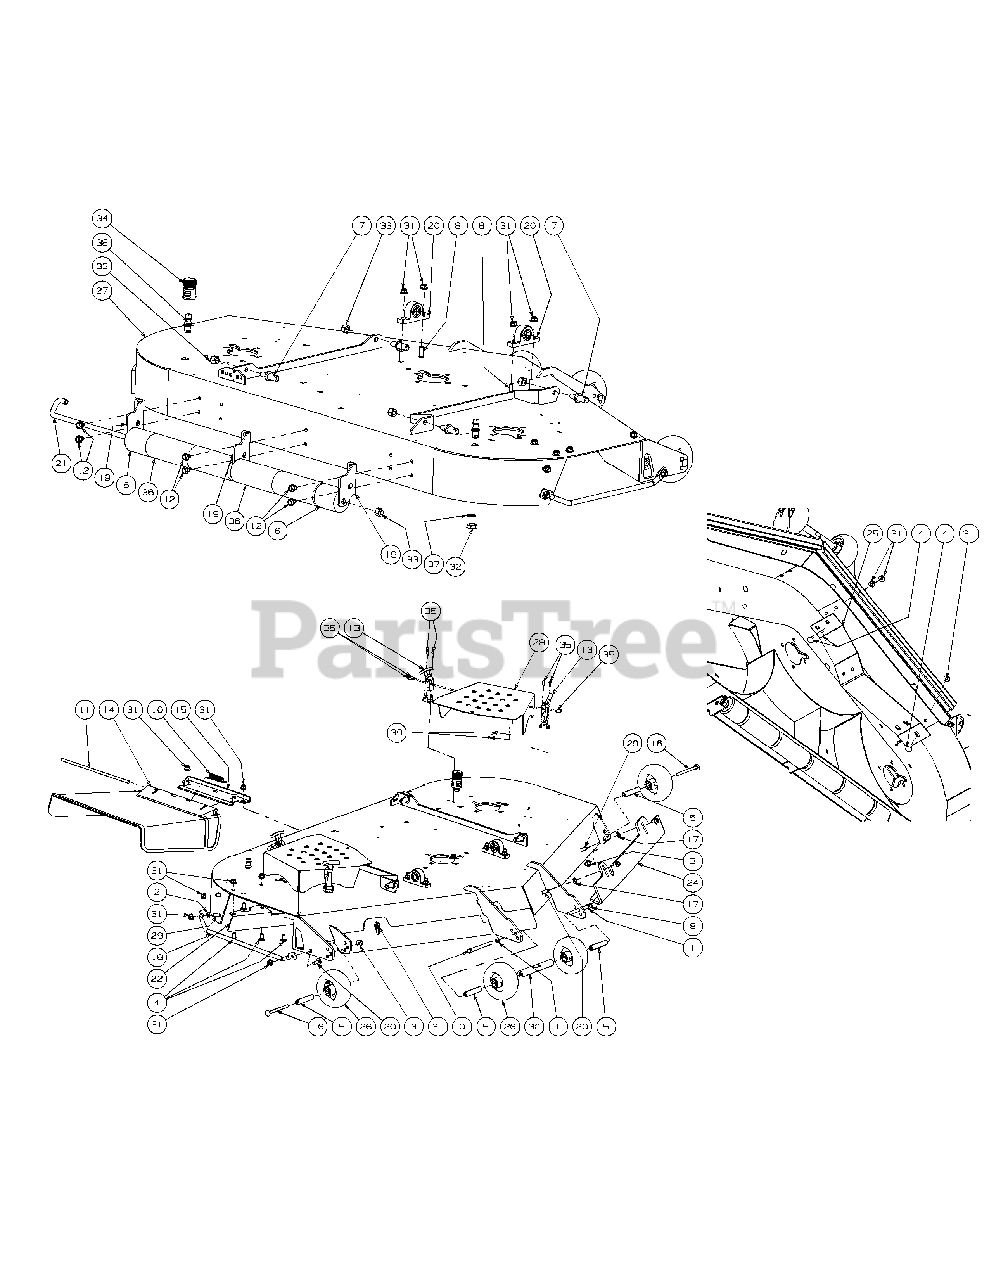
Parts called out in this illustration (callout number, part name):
1	Lock Washer, 3/8
2	Washer, 3/8
3	Flange Lock Hex Nut, 3/8-16
4	Carriage Bolt, 3/8-16 x .75 Lg.
5	Wheel Spacer
6	Grass Catcher Roller
7	Pin, 5/8 Dia. x 1.2 Lg.
8	Carriage Bolt, 3/8-16 x 1.00
9	Hex Cap Screw
10	Torsion Spring, 0.4ID x 2.16Lg
11	Chute Deflector Rod
12	Hex Index Washer Screw, 3/8-16, .5
13	T-Handle Latch Draw
14	Chute Deflector
15	Chute Deflector Bracket
16	Carriage Bolt, 3/8-16 x 4.00
17	Push Retainer
18	Finger Guard
19	Grass Catcher Roller Bracket
20	Lift Pillow Block Standard
21	J-Hook w/ Threaded Roller
23	Right Hand Front Adjustment Skirt
24	Left Hand Front Adjustment Skirt
25	Baffle, 60" Adjustment
26	Complete Wheel, 5.00 Dia.
27	60" Deck Assembly
28	Deck Belt Cover
29	Carriage Bolt, 3/8-16 x 1.00
30	Ball Wheel Mounting Shaft
31	Lock Nut, Nylon Insert
32	Hex Nut, M16-1.5
33	Lock Nut, Nylon Insert, 1/2-13
34	Water Nozzle Adaptor
35	Phillips Head Screw, 10-32
36	Front Roller
37	Lock Washer, 17 x 23.8 x 1.95
38	Deck Water Nozzle
39	Lock Nut, Nylon Insert, 10-32
